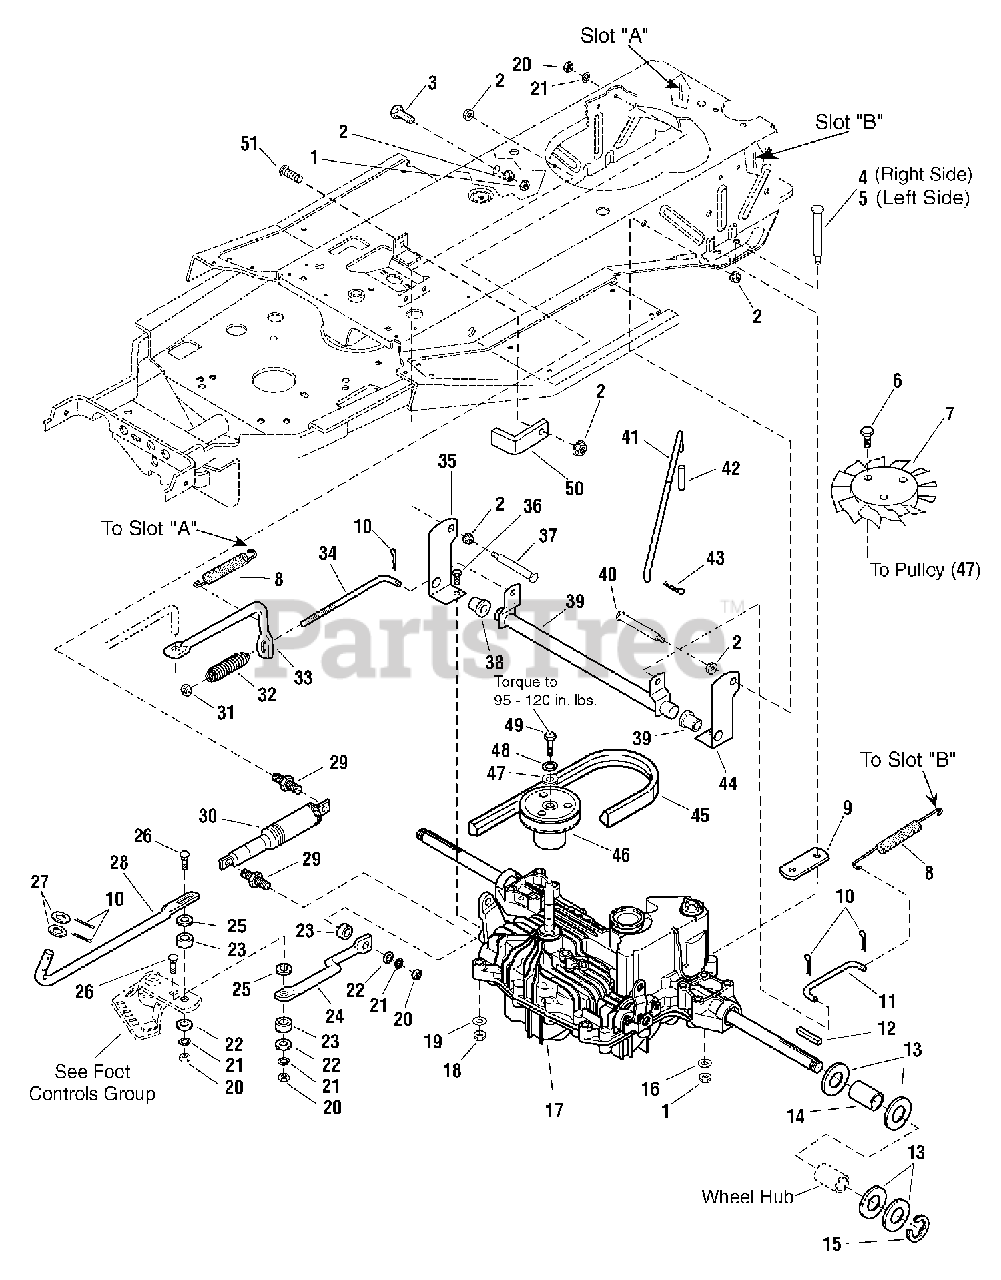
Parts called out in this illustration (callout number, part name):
1	LOCKNUT, 5/16-18
2	LOCKNUT, Small Flange, 5/16-18
3	CAPSCREW, Hex Head, 5/16-18 x 1
4	CAPSCREW, Hex Head, 5/16-18 x 2-3/4, RH
5	CAPSCREW, Hex Head, 5/16-18 x 3-1/4, LH
6	SCREW, Hex Washer Head, Taptite, 1/4-20 x 1-1/8
7	FAN, 10 Blade Nylon
8	SPRING, Extension
9	SPACER, Rectangular, 1 x 3 x 1/4
10	PIN, Cotter
11	ROD, Brake Link
12	KEY
13	WASHER, 3/4
15	RING, Retaining, External, 3/4
16	WASHER, 5/16, 0.13 Thick
17	TRANSAXLE, TuffTorq K51, See Transmission Service Parts - Tuff Torq K51 Transaxel
18	LOCKNUT, Flange, 5/16-18
19	WASHER, 5/16, 0.06 Thick
20	NUT, 5/16
21	LOCKWASHER, 5/16
22	WASHER, 5/16
24	ROD, 2 Bends Flat Ends, 10" Long
25	WASHER, 5/16
26	CARRIAGE BOLT, 5/16-18 x 1-1/4
27	WASHER, 1/2
29	STUD, 5/16-18 x 57/64
30	SHOCK ABSORBER
31	LOCKNUT, 3/8-16
32	SPRING, Compression
33	ROD, Brake Guide, 7" Long
35	STRAP, Torque, RH
36	CAPSCREW, Hex Head, 5/16-18 x -1/2
37	CAPSCREW, Hex Head, 5/16-18 x 2-3/4
39	SHAFT & ARMS ASSEMBLY
40	CAPSCREW, Hex Head, 5/16-18 x 5-1/2
41	ROD, 5 Bends. 11.34" Long
43	PIN, Cotter, 5/8 x 3/4
44	STRAP, Torque, LH
45	BELT, Drive
46	PULLEY ASSEMBLY
47	WASHER, 1/4
48	LOCKWASHER, 1/4
49	CAPSCREW, Hex Head, Metric M06-1 x 20mm, 8.8
50	BRACKET, Limit Speed Control
51	CARRIAGE BOLT, 5/16-18 x 5/8
